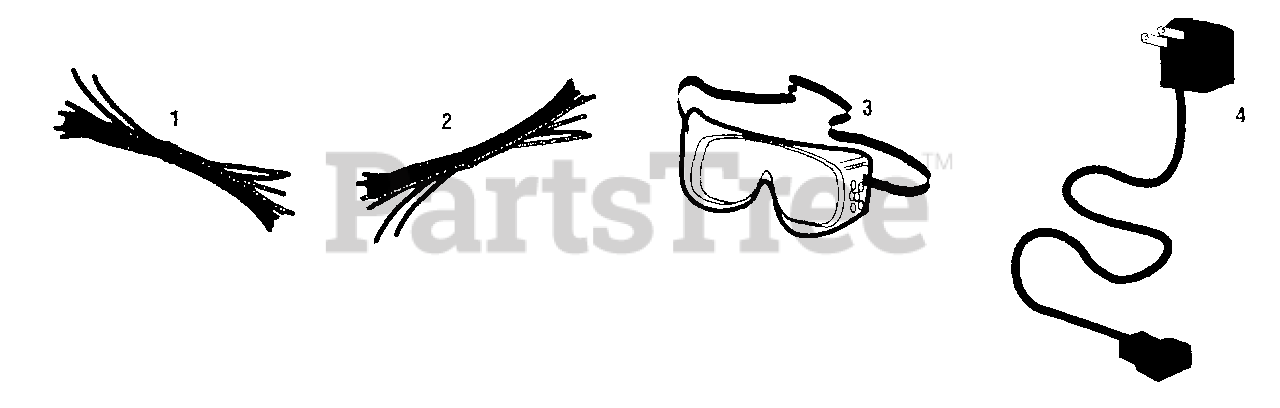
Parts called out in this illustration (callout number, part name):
1	Trimmer String Kit, .155"
2	Trimmer String Kit, .130"
3	Safety Goggles
4	Battery Charger
